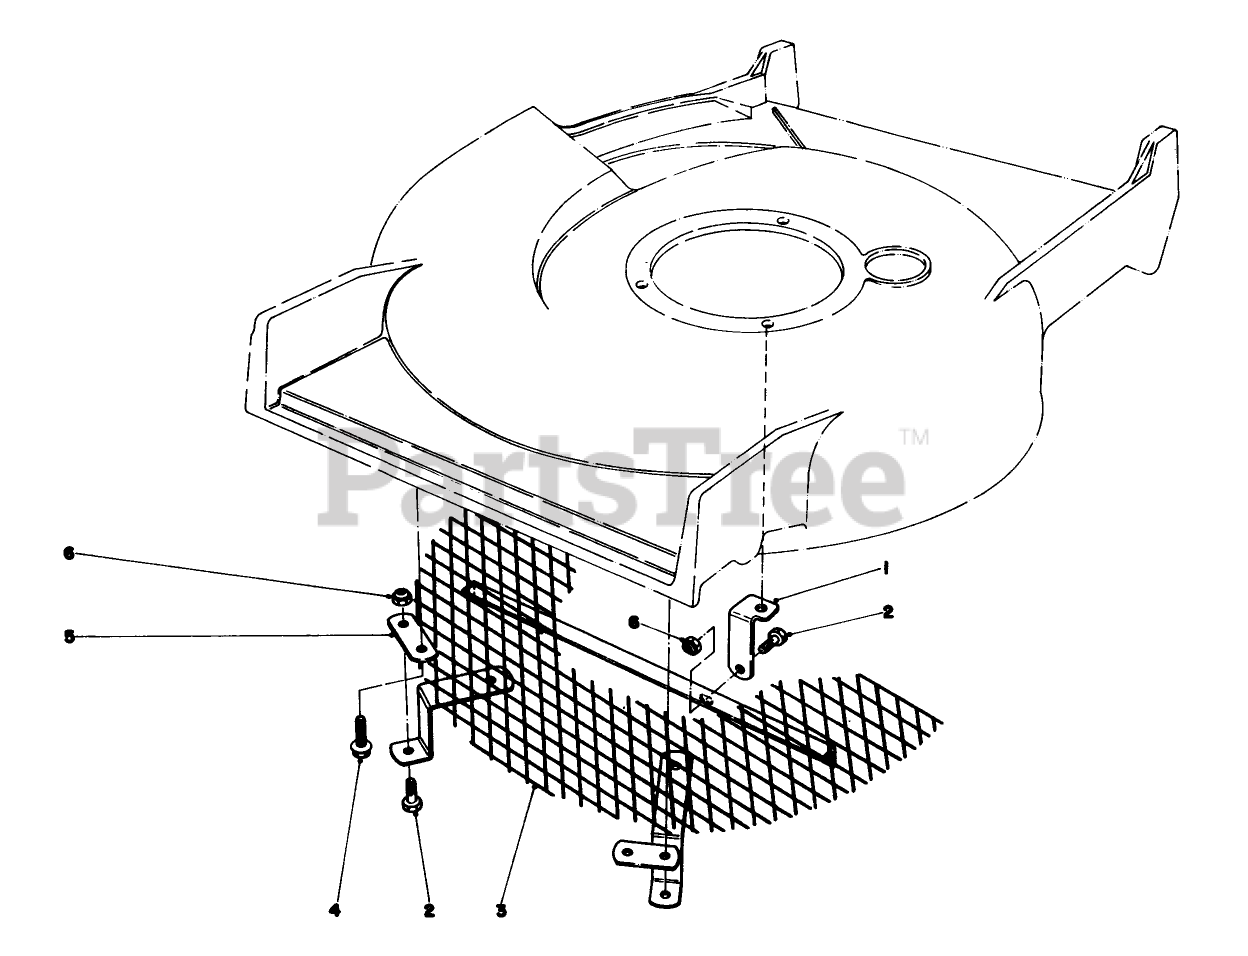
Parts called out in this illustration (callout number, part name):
2	SCREW-HH
4	SCREW-THD ROLL, HWH
6	NUT-LOCK, NI
